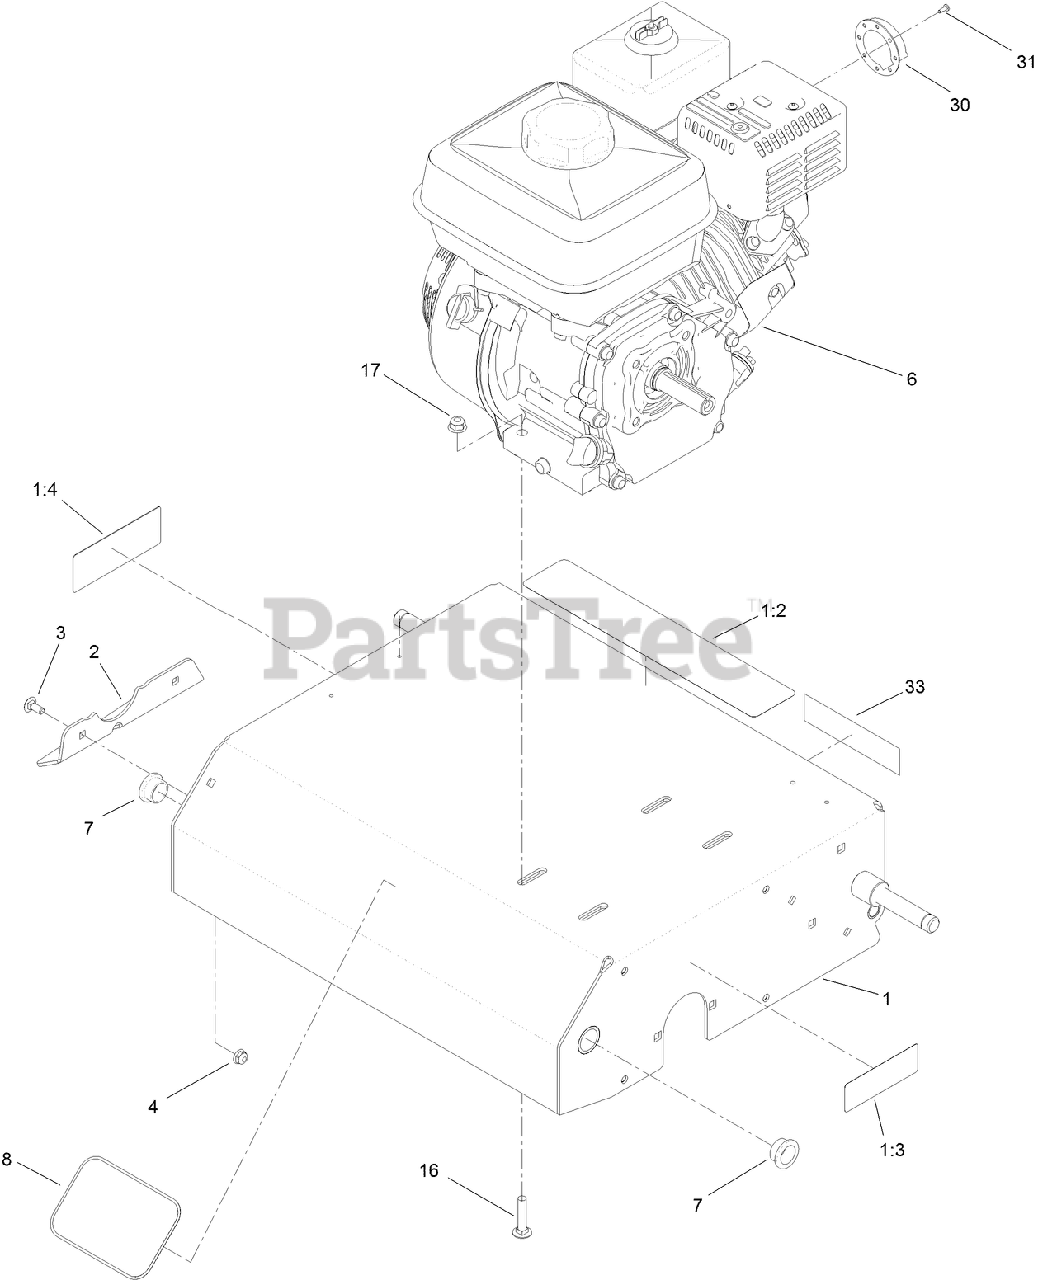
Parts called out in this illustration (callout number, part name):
1	FRAME ASM
1:2	DECAL-WARNING
1:3	DECAL-WARNING, SHIELDS
1:4	DECAL-DANGER
2	GUARD-HAND
3	SCREW-CARR
4	NUT-HF
7	BUSHING
8	DECAL
16	BOLT-CARR
17	NUT-HF, NI
30	DEFLECTOR
31	SCREW-PPHTF
33	DECAL-ARRESTER, SPARK
